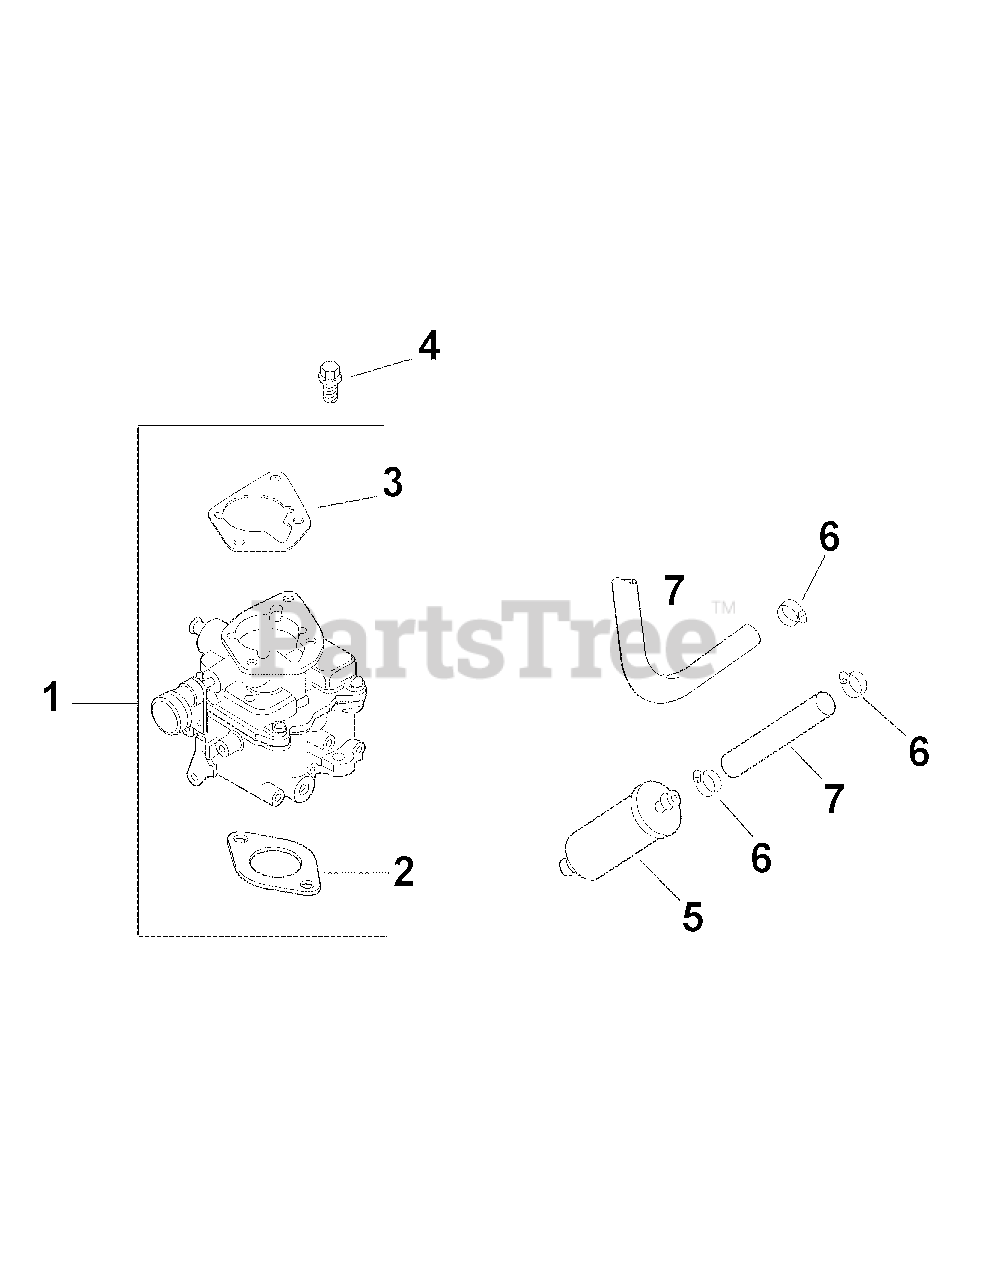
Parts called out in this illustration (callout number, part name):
1	Kit, carburetor w/gasket (Includes 2,3)
2	Gasket, air cleaner base
3	Gasket, carburetor
4	Screw, hex. Flange M6x1.0x25 (2)
5	Filter, fuel
6	Clamp, hose (4)
7	Line, fuel 24" - cut to length (2)
